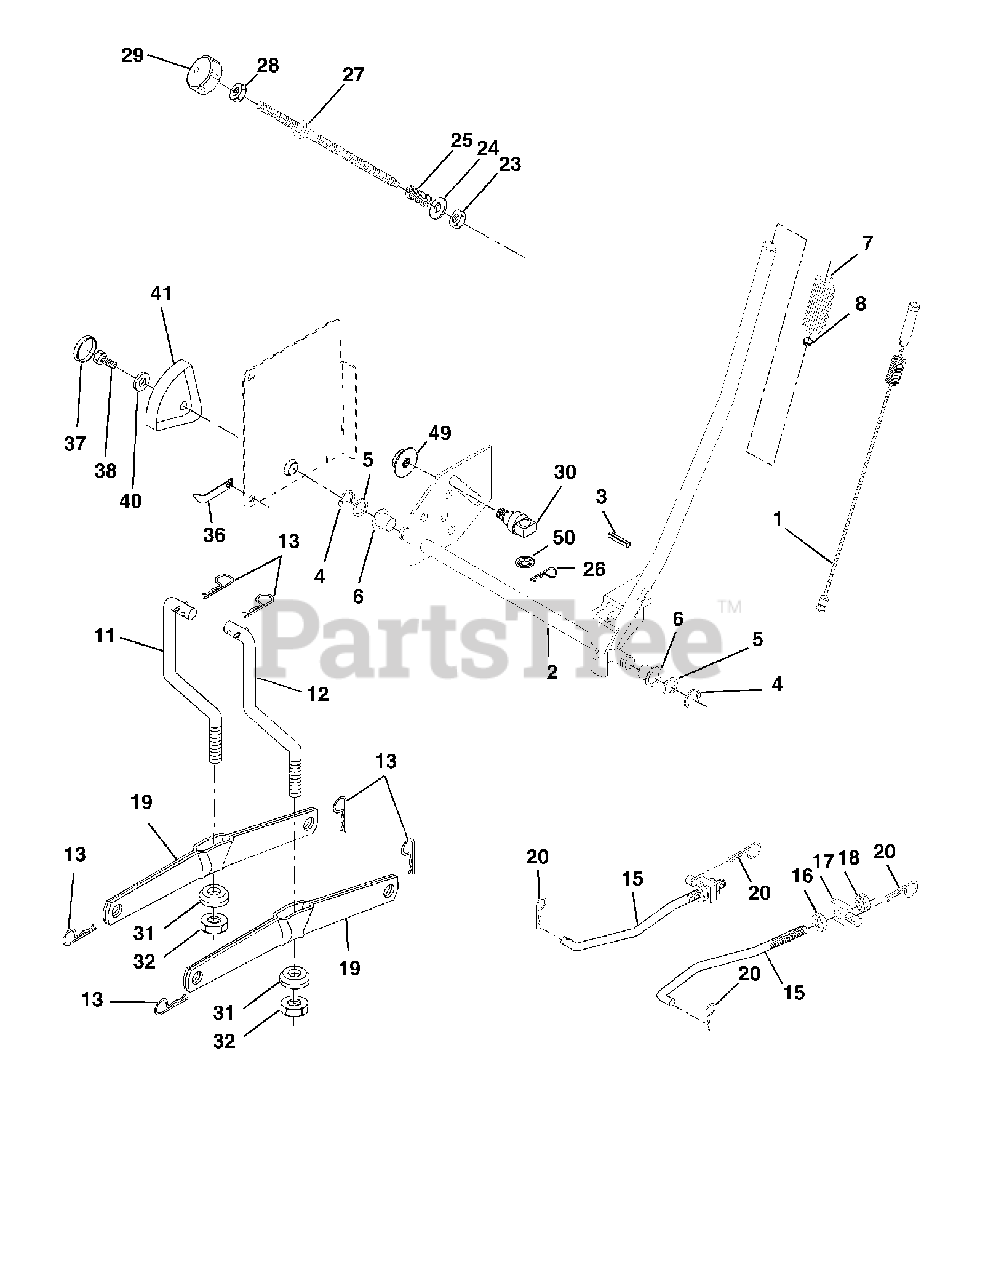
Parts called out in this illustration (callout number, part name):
1	WIRE ASM INNER W/ PLUNGER LT
2	SHAFT ASM R HANDLE
3	PIN GROOVE.
4	RETAINING RING LT
6	BEARING.NYLON
7	GRIP HANDLE
11	LINK LIFT LH
12	Lift Link Assembly, RH
13	RETAINER-SPRNG RB
15	LINK.SUSPENSION.FRONT
16	NUT.HEX.JAM.1/2-13
18	NUT.LK.W/WSH.1/2.
19	ARM.REAR.SUSPENSION
20	SPRING RETAINER
24	WASHER
26	RETAINER CLIP
27	ROD ADJ LIFT
28	NUT
29	KNOB INF 3/8-16
30	TRUNNION
31	BEARING.PIVOT.LIFT
32	NUT CROWNLOCK 3/8-24
36	POINTER, HEIGHT INDICATOR
37	PLUG,HOLE
38	SCREW 5/16-18X1
41	IND. HEIGHT STLT
49	Flange Hex Lock Nut, 3/8-16
50	NUT PUSH M
